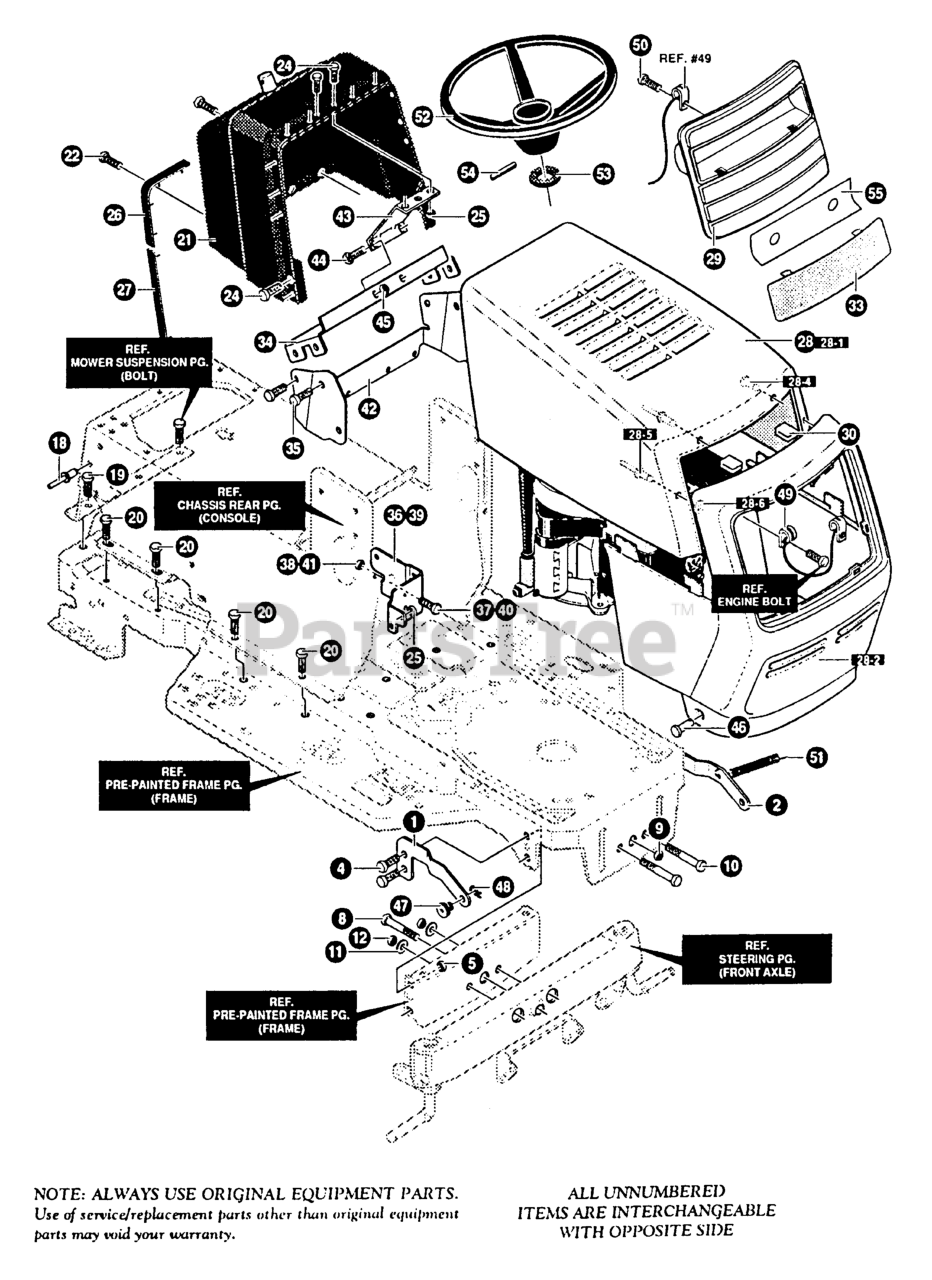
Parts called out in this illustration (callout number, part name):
1	BRACKET, HOOD
2	BRACKET, HOOD
4	SCREW, 5/16-18 x 0.75
5	NUT, 5/16-18
8	BOLT, .625 X 2.18
9	NUT, 1/2-13
10	SCREW, 3/8-16 x 3.00
11	WASHER, .39ID X 1.25D X .07
12	NUT, 3/8-16
18	RIVET, POP
19	SCREW
20	SCREW, 1/4-20 X .50
22	SCREW, 1/4-14 X .75
24	SCREW, 10-24 X .63
25	NUT, #10-24
26	BUMPER, HOOD/DASH
27	BUMPER, HOOD/DASH
28	HOOD ASSEMBLY
28-1	KIT, HOOD
28-2	HOOD KIT FOR K-MART
28-4	RIVET, POP
28-5	RIVET, POP
28-6	WASHER, FLAT .203 X .56 X .040
29	INSERT, GRILLE
30	CLIP, TINNERMAN
34	SUPPORT, STEERING PTO
35	SCREW, 1/4-20X.38
36	BRACKET, DASH/TANK, RH
37	SCREW, 1/4-20 X .75
38	NUT, 1/4-20
39	BRACKET, DASH/TANK, LH
40	SCREW, 1/4-20 X .75
41	NUT, 1/4-20
42	SUPPORT, LOWER DASH
43	DASH, SUPPORT BRACKET
44	SCREW, 1/4-20 X .75
45	NUT, 1/4-20
46	PIN, CLEVIS
47	BEARING HOOD
48	PIN, HAIR
49	LANYARD, HOOD 11.75
50	SCREW, 1/4-10 X .75
51	SPRING, HOOD LATCH
52	STEERING WHEEL
53	SPACER, SLEEVE
54	PIN, SPRING
55	FOIL, LENS REFLECTOR
